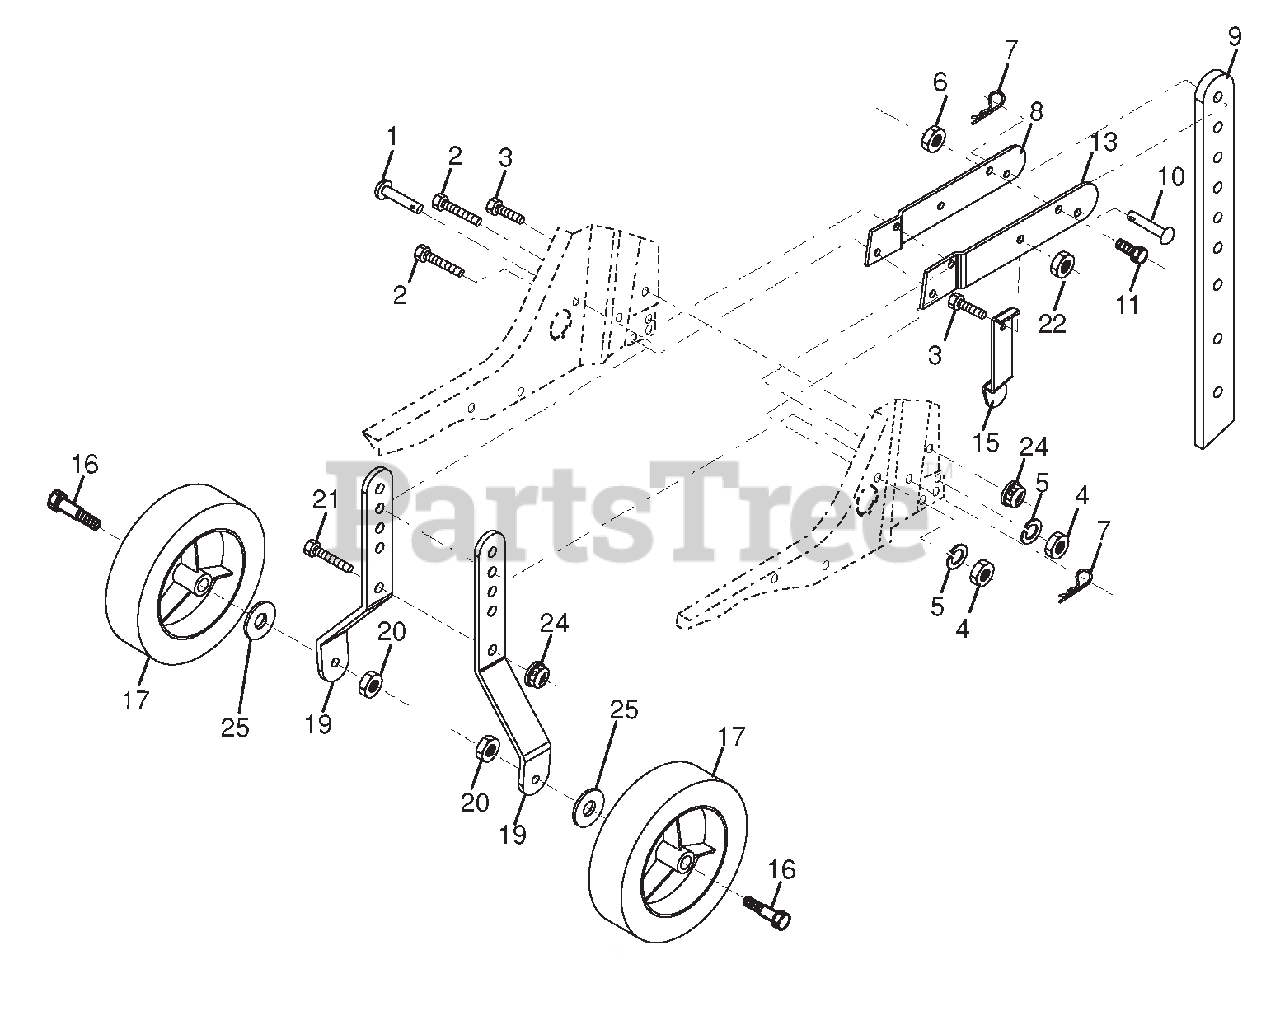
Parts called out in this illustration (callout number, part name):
1	Pin, Clevis
2	Bolt, Hex Head 5/16-18 x 1-1/4
3	Bolt, Hex Head 5/16-18 x 3/4
4	Nut, Hex 5/16-18
5	Washer, Lock 5/16
6	Locknut, Washer Insert 3/8-16
7	Clip, Hairpin
8	Support, Depth Stake, R.H.
9	Stake, Depth
10	Pin, Clevis
11	Bolt, Hex Head 3/8-16 x 1-3/4
13	Support, Depth Stake, L.H.
15	Spring, Stake
16	Bolt, Shoulder
19	Bracket, Wheel
20	Nut, Hex, Crownlock 3/8-16
21	Bolt, Hex Head 5/16-18 x 1
22	Locknut, Washer Insert 5/16-18
24	Nut, Hex, Flangelock
25	Washer, 17/32 x 7/8 x 16 Ga.
